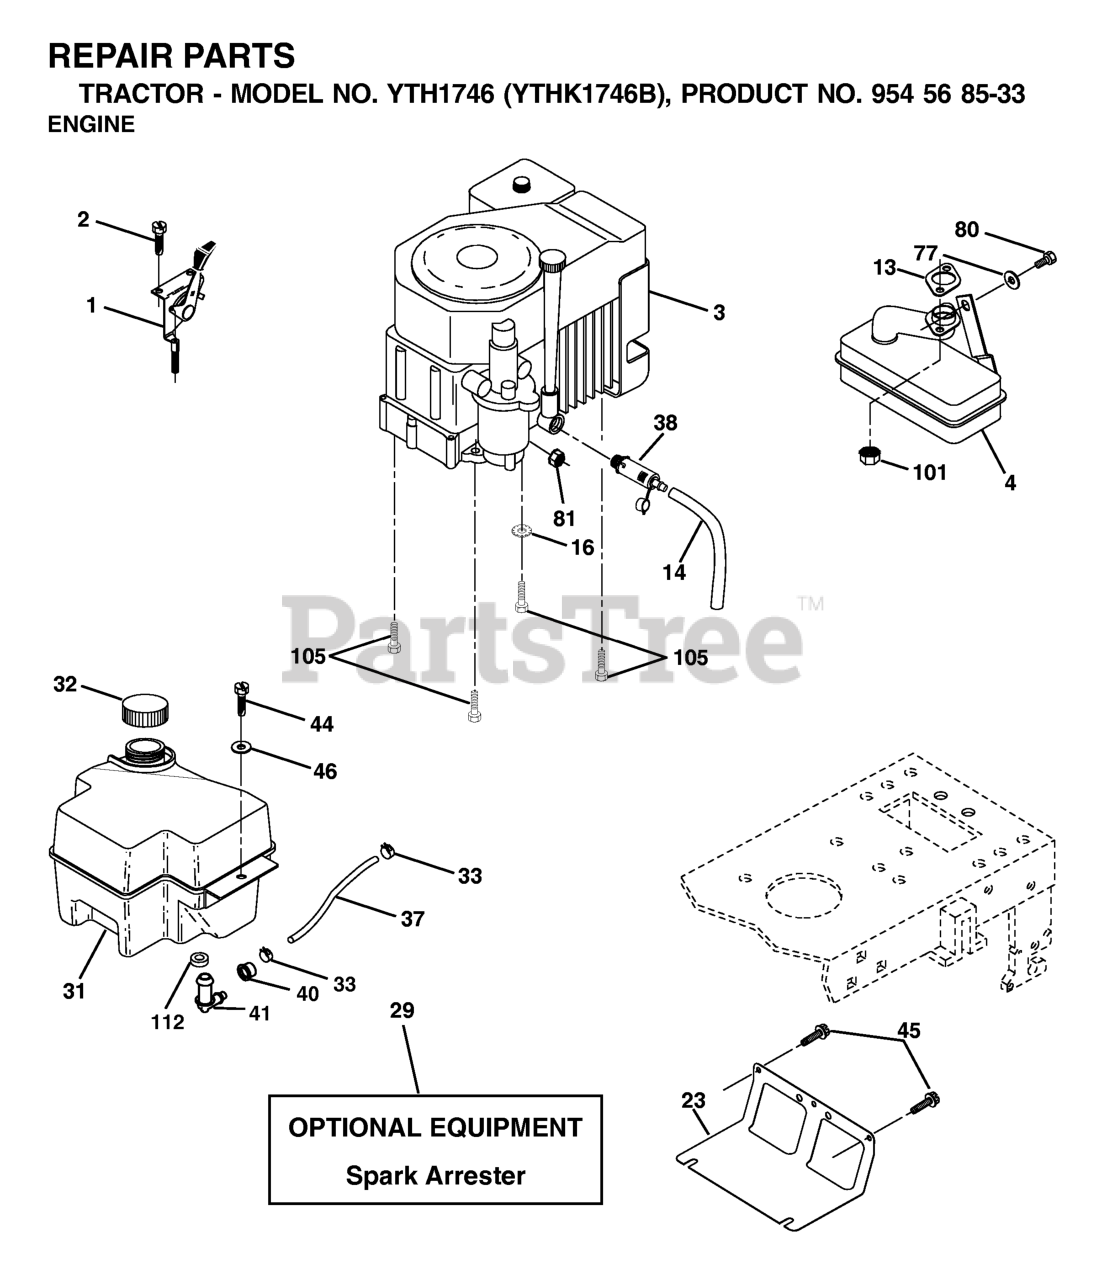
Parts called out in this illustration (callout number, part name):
1	CONTROL.THROTTLE.LT/YT
2	SCREW
14	TUBE, DRAIN OIL ASM.
16	LOCKWASHER
23	SHIELD.BROWNING.DBR.GUARD
29	KIT.SPARK ARRESTOR 794945 B&S
31	GAS TANK 2GAL
32	FUEL CAP
33	HOSE CLAMP
37	LINE.FUEL.20
38	PLUG, OIL DRAIN EASY
40	BUSHING.SNAP.NYL.BLK.
41	STEM FUEL TANK
44	SCREW HEXWSHR 1/4-20X3/4
45	SCREW, 3/8-16X3/4
77	WASHER
80	Bolt, Hex Head, Fin. 5/16-18 x 1/2
81	NUT
101	FLANGE NUT
105	SCREW 3/8-16X1
112	BUSHING OUTLET T
